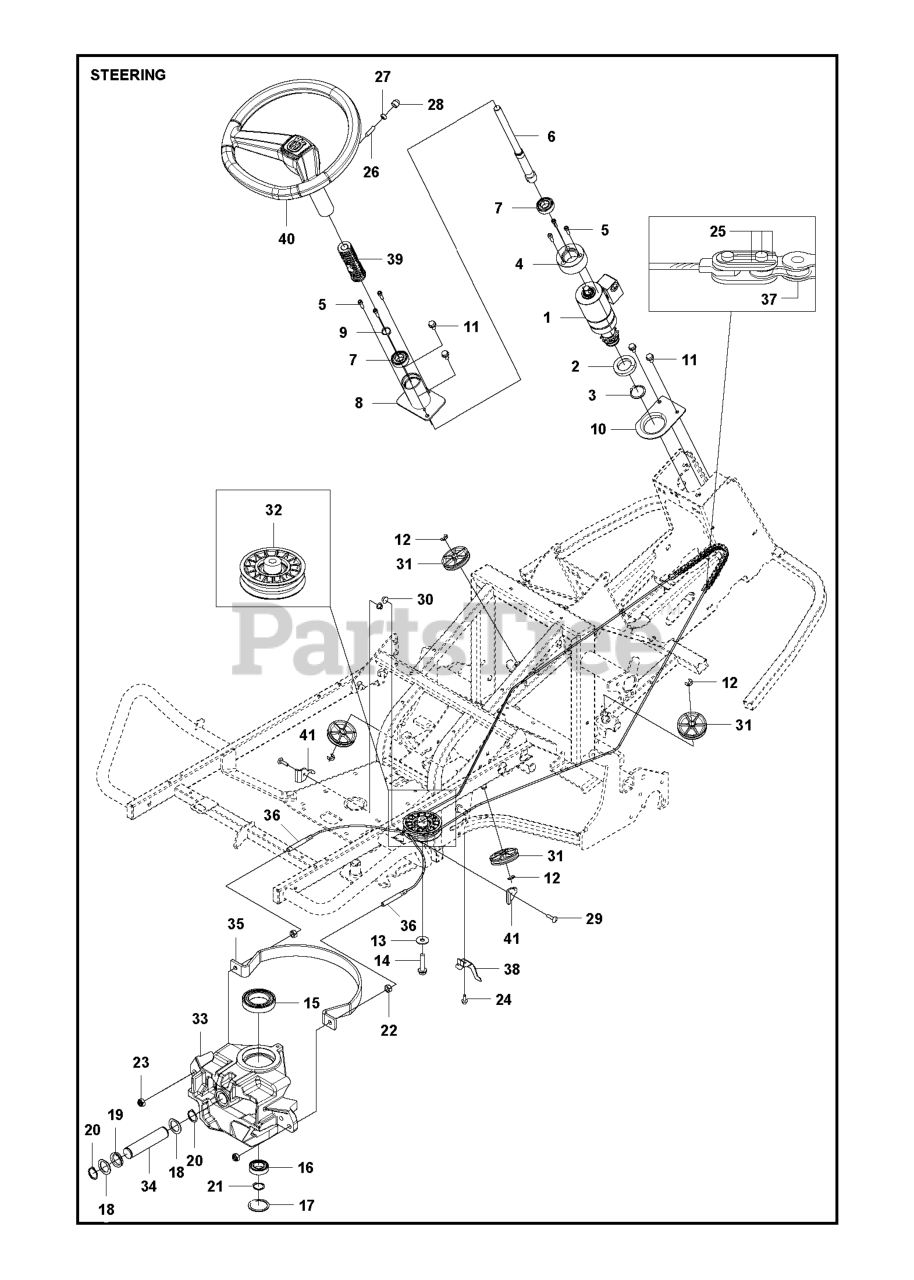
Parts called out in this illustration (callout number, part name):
1	COMFORT STEERING
5	SCREW MC6S 6X20
7	BALL BEARING 6004-2RS1
9	RETAINING RING SGA 20
12	RETAINING RING
14	COLLAR SCREW
15	BALL BEARING 6010 2RS1
16	Ball Bearing 6005-2rs
17	CIRCLIP SGH 47
20	Retaining Ring
21	RETAINING RING SGA 25
22	NUT
23	NUT
27	NUT
28	PROTECTIVE COVER
30	NUT FLANGE
39	DRIVER STEERING WHEEL
40	STEERING WHEEL
